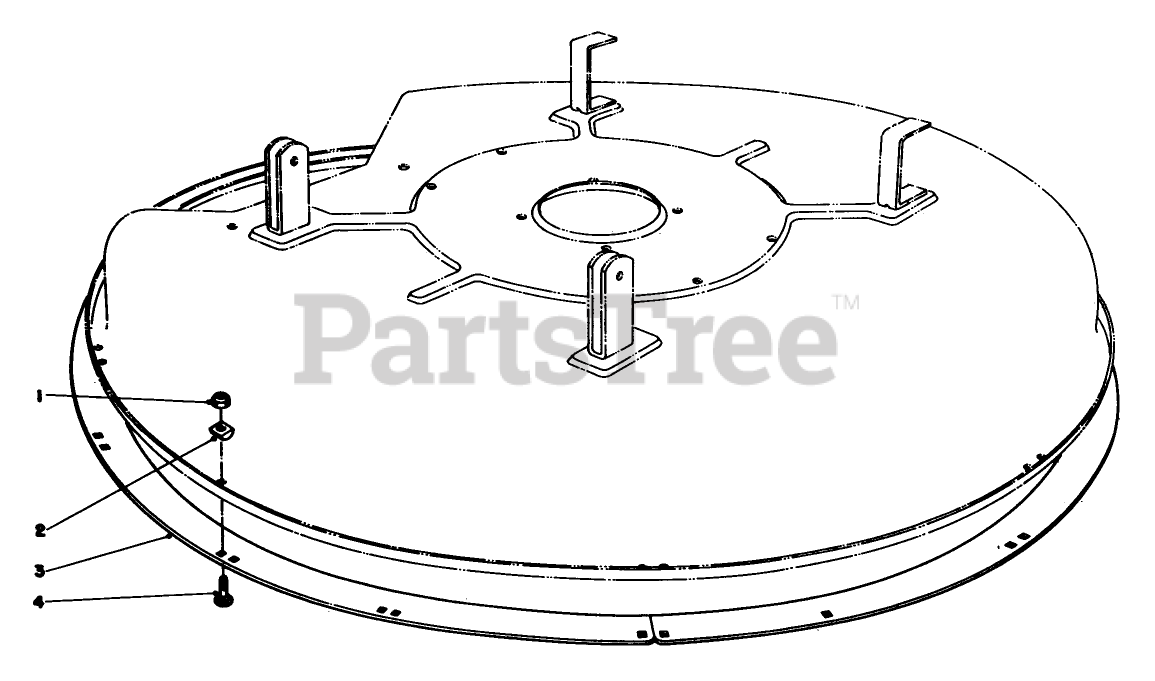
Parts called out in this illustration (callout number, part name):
1	NUT-LOCK, NI
3	DECK RING *B
4	BOLT-CARR
